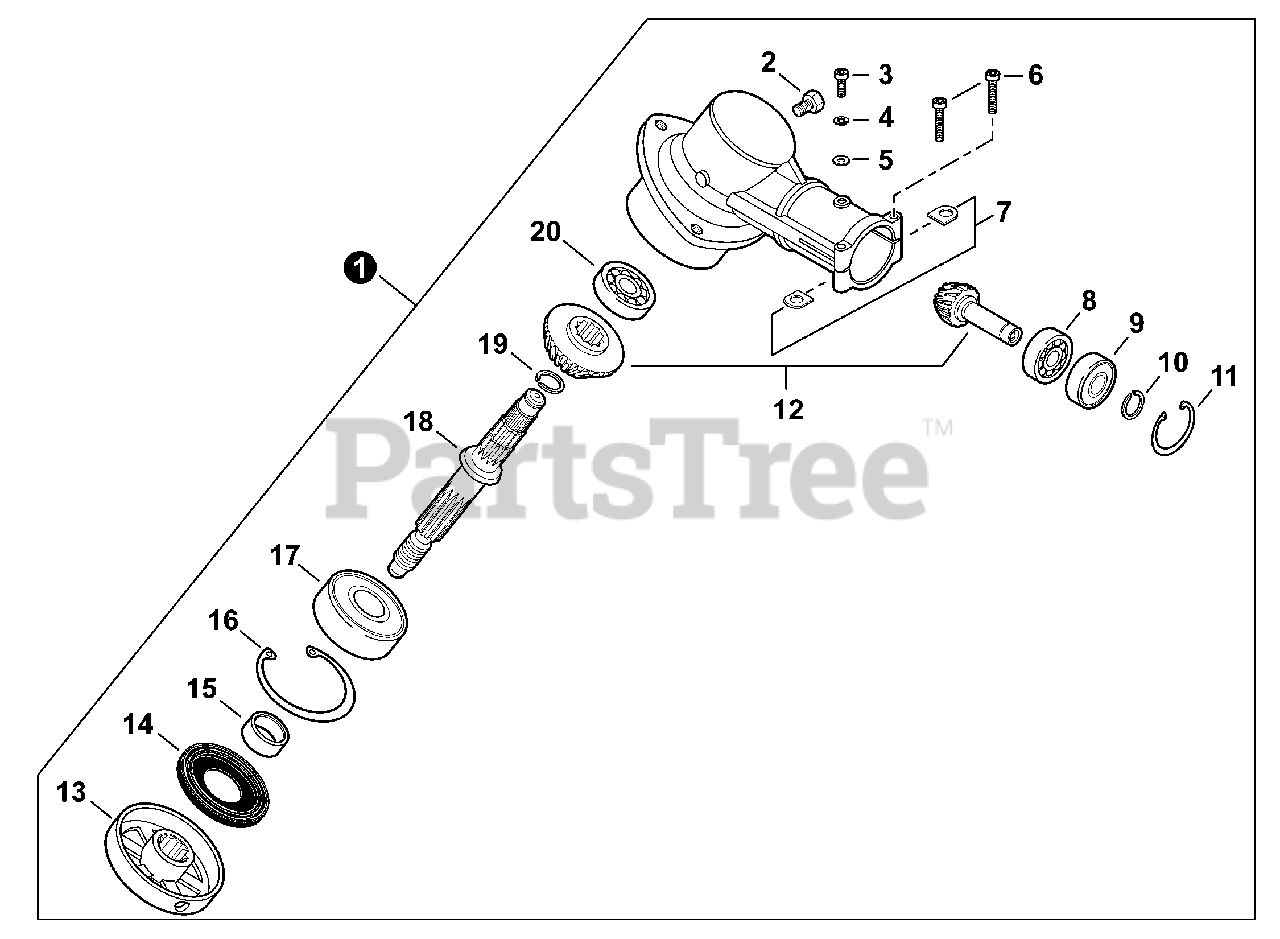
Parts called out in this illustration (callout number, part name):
1	GEAR CASE ASSY
2	BOLT M8×8
3	BOLT, TORX 5×10
4	WASHER, SPRING 5
5	WASHER, FLAT 5.5×10×0.8
6	BOLT, TORX 5×25
8	BEARING, BALL 6900
9	BEARING, BALL 6900Z
10	RING, SNAP Ø10
11	RING, SNAP Ø22
12	GEAR SET
13	PLATE, ADAPTOR - UPPER
14	SEAL, OIL 22
15	SPACER 11.8×15×9
16	RING, SNAP Ø32
17	BEARING, BALL 6201
18	SHAFT, GEAR
19	RING, SNAP Ø12
20	BEARING, BALL 609
